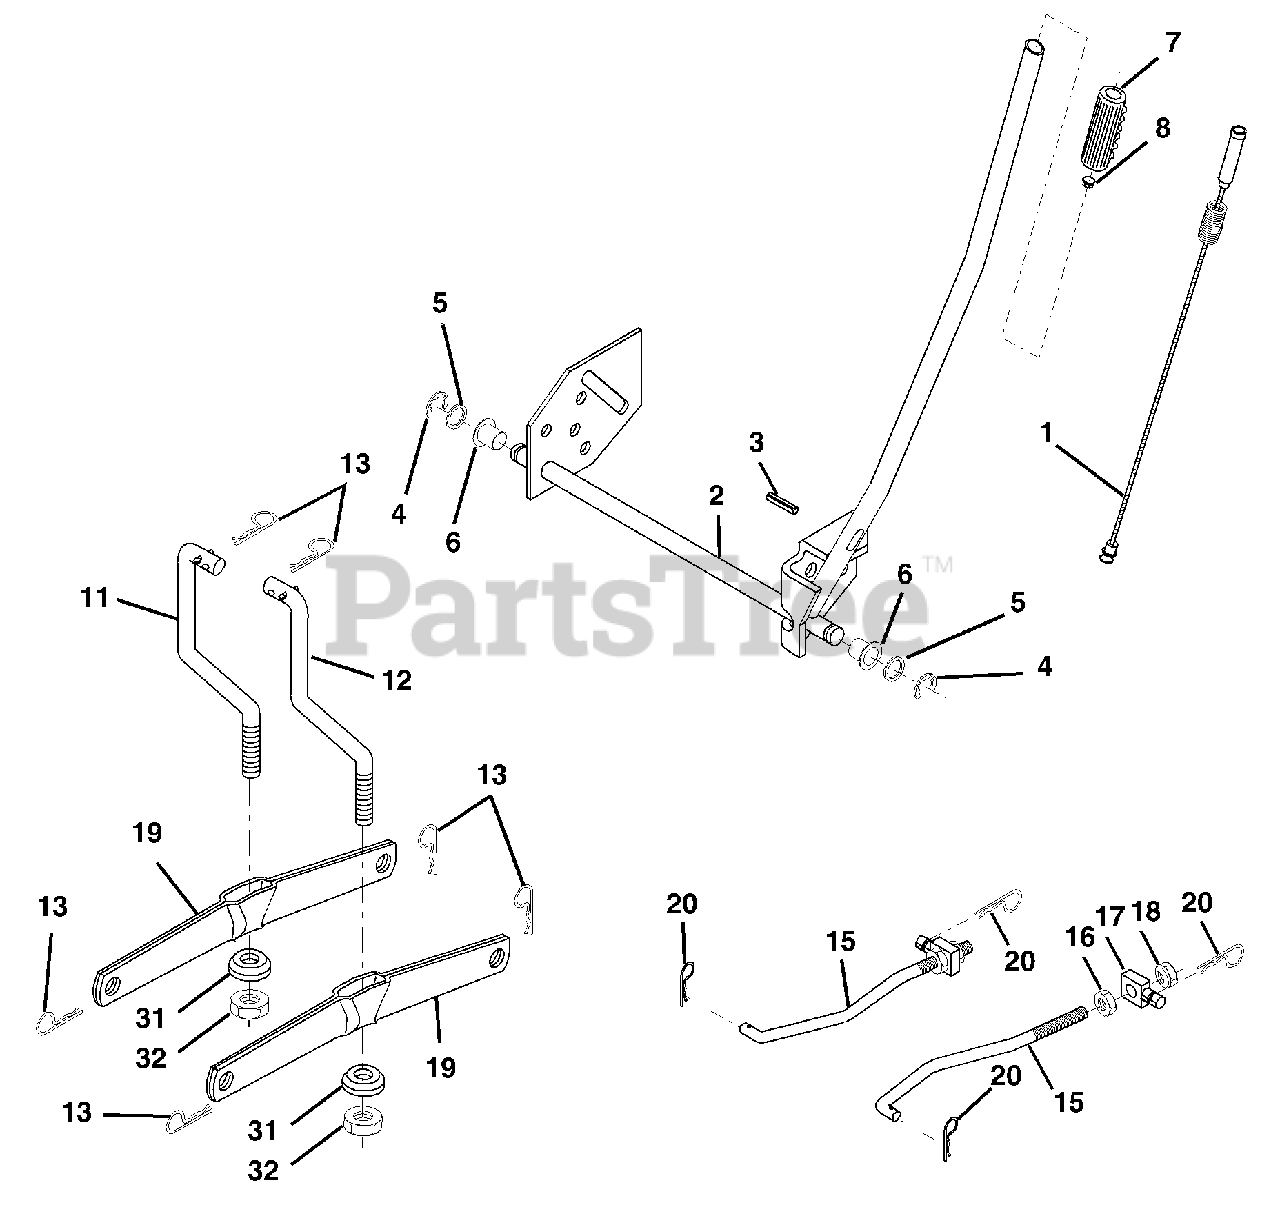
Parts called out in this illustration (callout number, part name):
1	Wire Asm Inner/Sprg W/plunger LT
2	Shaft Asm Lift RH w/Inf
3	Pin Groove 1 500 Zinc
4	E Ring #5133-62
5	Washer 21/32 x 1 x 21 Ga.
6	Bearing Nylon Blk 629 Id
7	Grip Handle
8	Button Plunger
11	Link Lift LH Fixed Length
12	Link Lift RH Fixed Length
13	Retainer Spring
15	Link Front
16	Nut Jam Hex 1/2-13 unc
17	Trunnion
18	Nut Lock W/Wsh 1/2-13 unc
19	Arm Suspension Rear
20	Retainer Spring
31	Bearing Pvt Lift
32	Nut Crownlock 3/8 - 24
